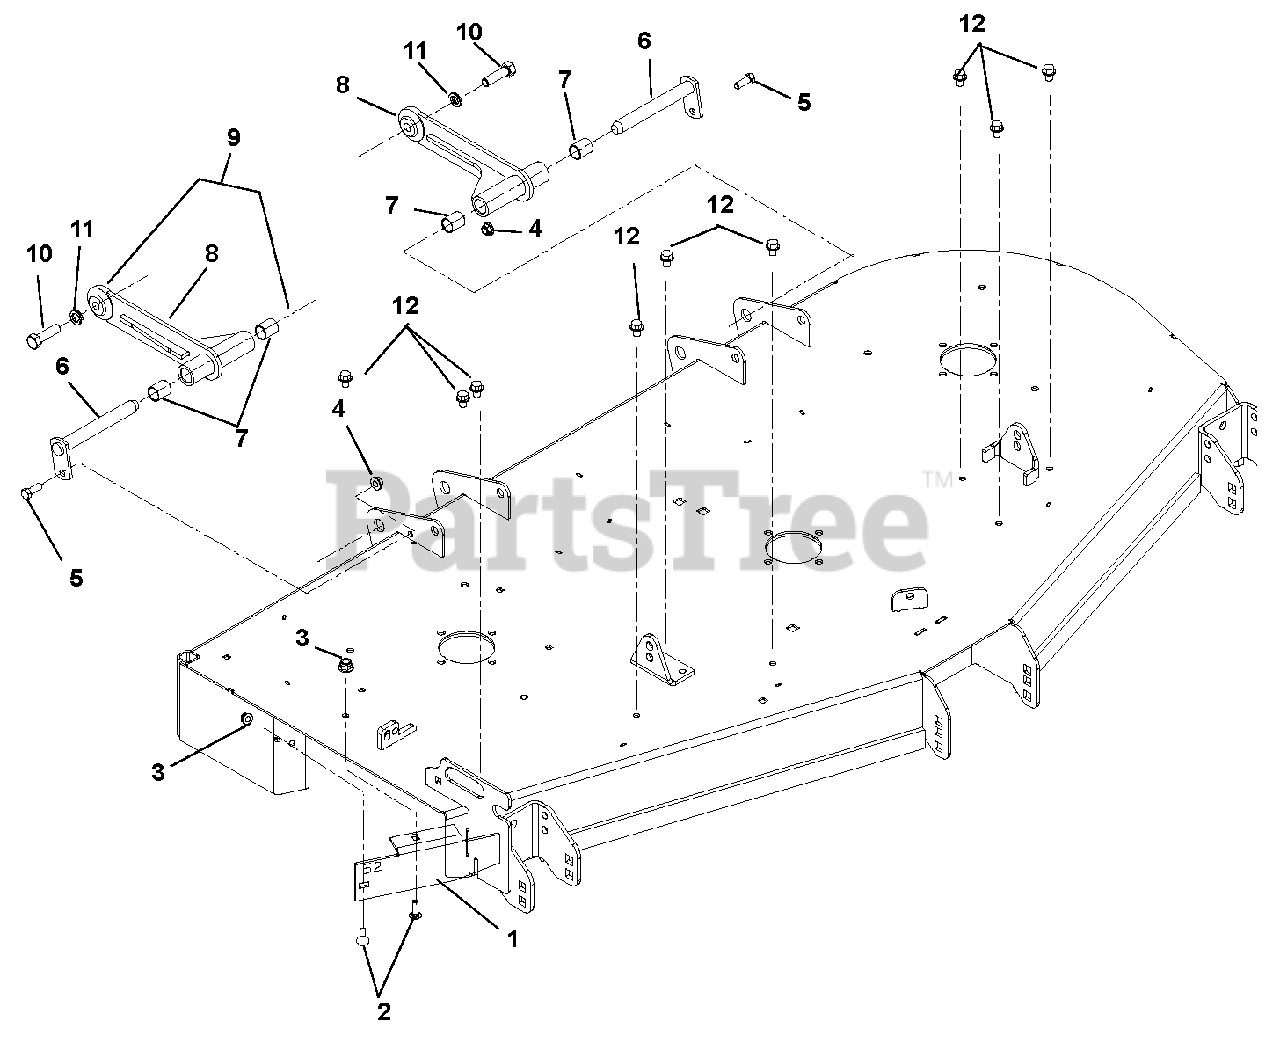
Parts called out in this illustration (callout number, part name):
1	Discharge Baffle, 44" & 48" (991082, 090, 098, 099)
1	Discharge Baffle, 60" (991084, 101)
1	Discharge Baffle, 52" (991083, 100)
2	Bolt, Round Head Square Neck .31-18 x 1.00 Grade 5
3	Nut, .31-18 Nyloc Flange
4	Nut, .38-16 Nyloc Flange
5	Bolt, Hex .38-16 x 1.00 Grade 5
6	Weldment, Mower Mounting Pin
7	Bearing, .75 x .875 x 1.00
8	Deck Pusher Arm Weldment
9	Assembly, Mower Mount Arm (Includes items 7 and 8)
10	Bolt, Hex .50-13 x 1.75 Grade 5 EP80
11	Washer, Locking .50 x .125 Regular
12	Screw, Tapping .38-16 x .50 Hex Washer Head
